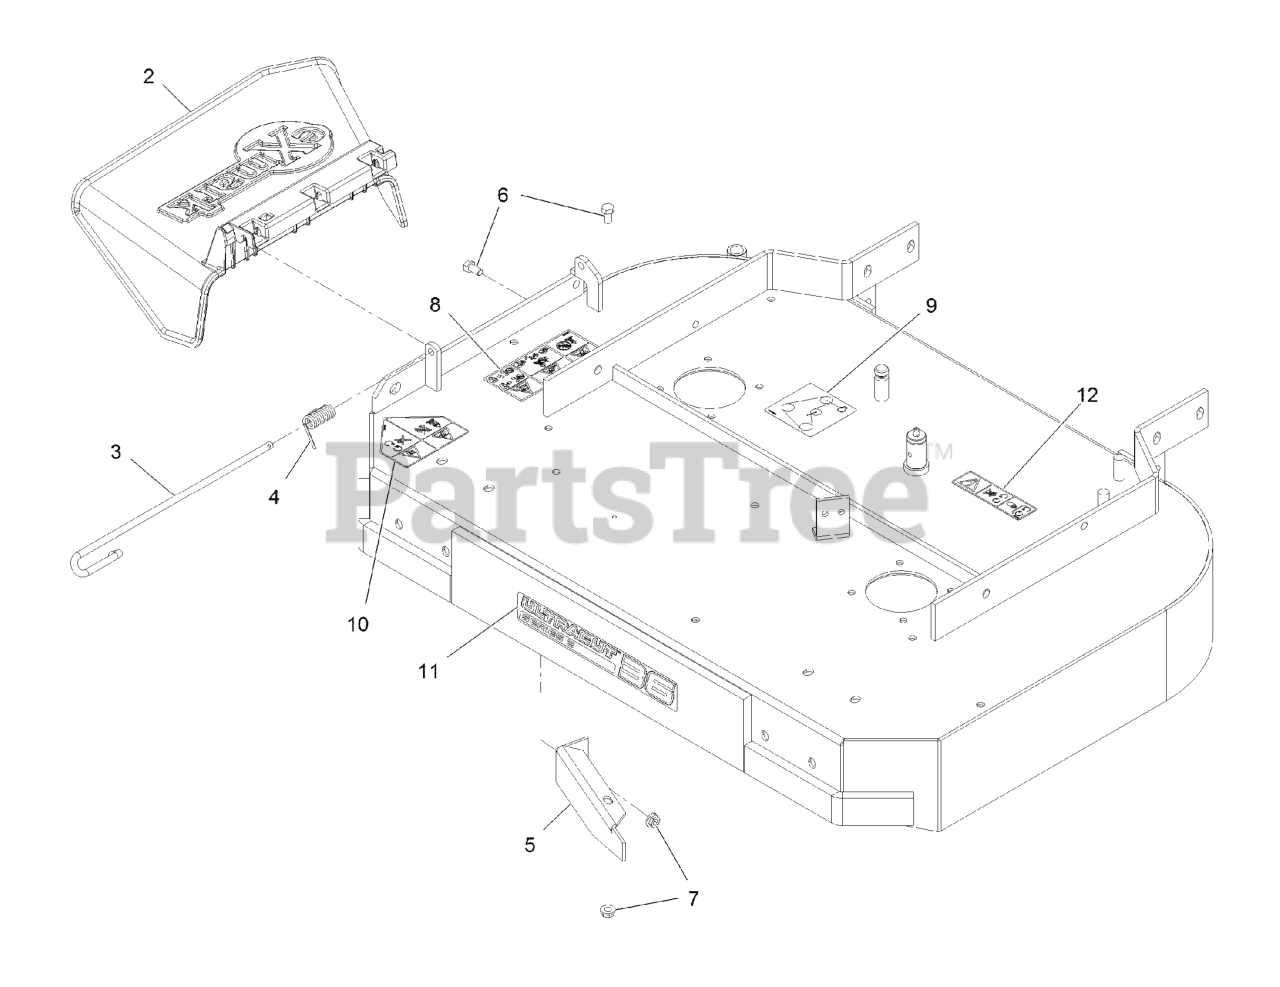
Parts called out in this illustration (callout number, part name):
2	CHUTE DEFLECTOR XRK M056
3	PIN-CHUTE
4	SPRING, TORSION
5	BAFFLE-DOGLEG
6	SCREW-HH
8	DECAL-WARNING THROWN OBJ
9	DECAL-BELT ROUTING 32-36
10	DECAL-DANGER
11	Decal-Ultracut 36 Series 2
12	DECAL-COVER, MISSING
